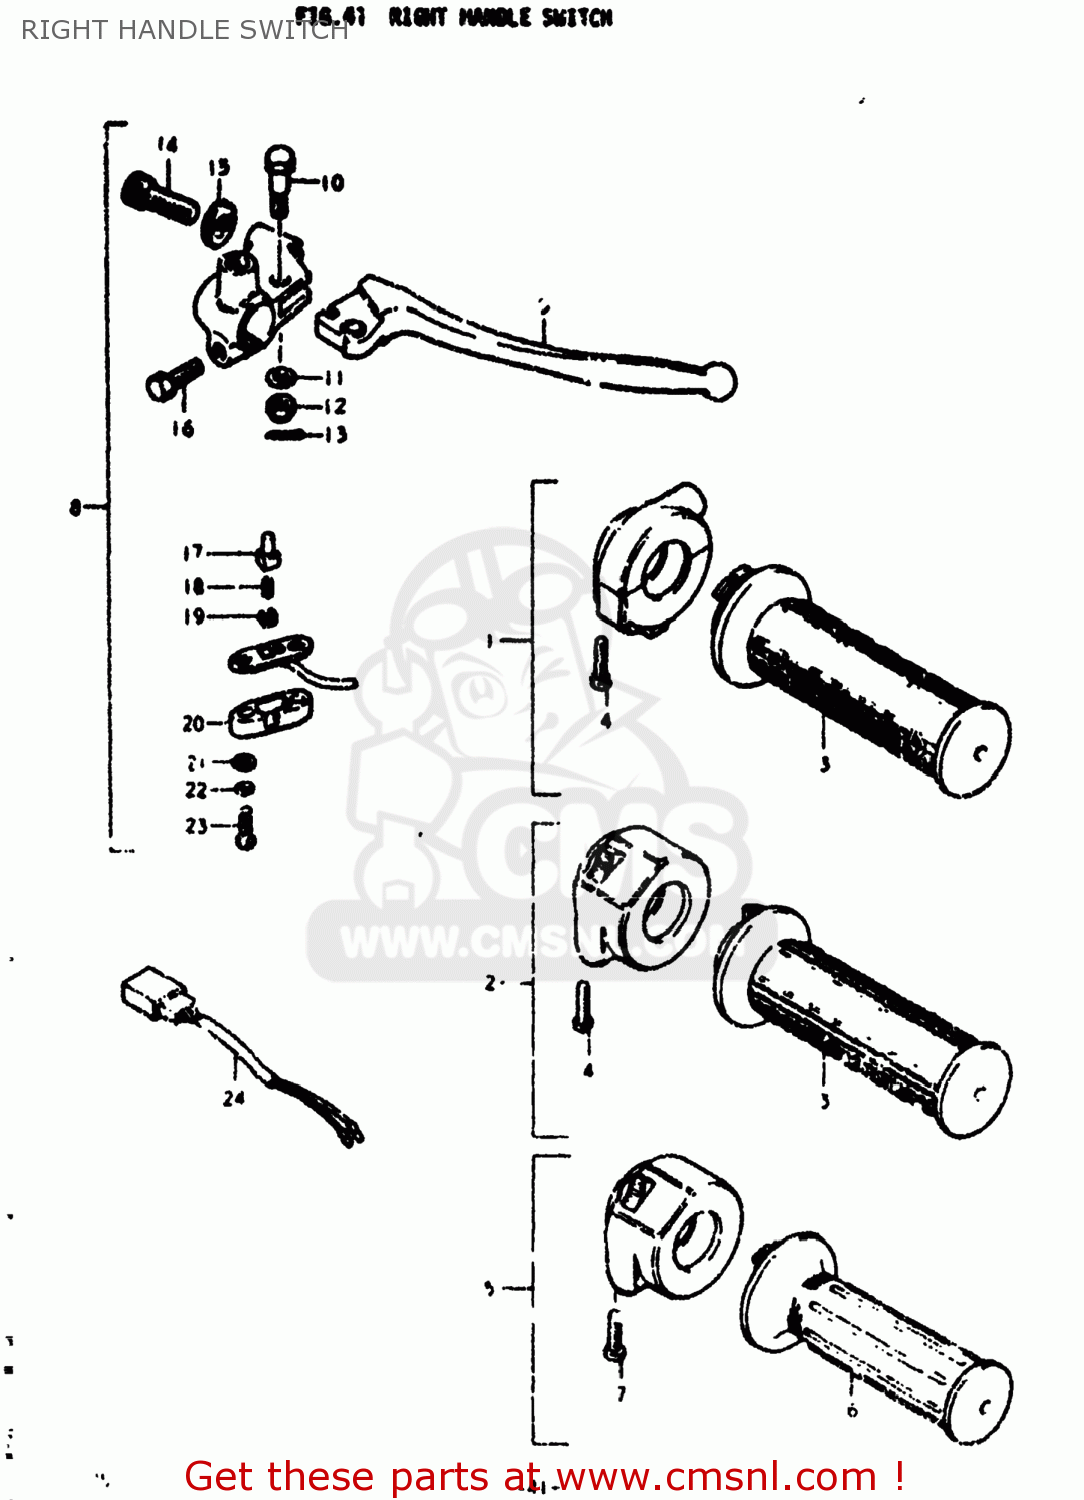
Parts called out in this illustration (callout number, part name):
1	GRIP ASSY,THROTTLE
2	GRIP ASSEMBLY,THROTTLE
3	GRIP,THROTTLE
4	SCREW
5	GRIP ASSEMBLY,THROTTLE
6	GRIP,THROTTLE
7	SCREW
8	LEVER ASSEMBLY,BRAKE
9	LEVER ASSEMBLY,ADJUST
10	BOLT,LEVER
11	LOCK WASHER
12	NUT,LEVER FITTNG
13	COTTER PIN
14	ADJUSTER,CABLE
15	NUT,CABLE ADJUSTER
16	BOLT
17	HOLDER
18	SPRING
19	PLATE
20	COVER,FR BK TERMINAL BASE
21	WASHER
22	WASHER,LOCK
23	SCREW
24	LEAD WIRE
